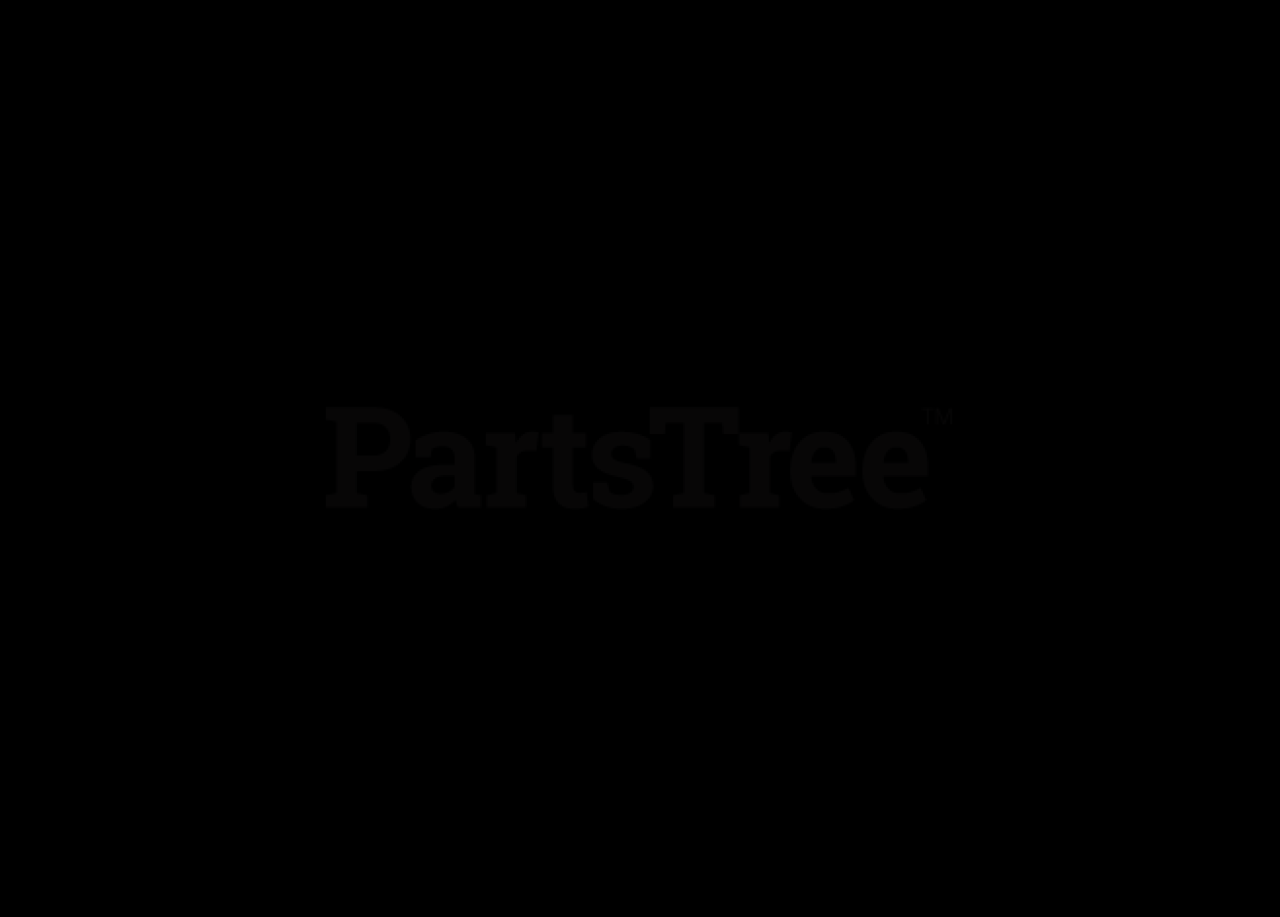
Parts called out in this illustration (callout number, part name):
1	Lift, Mower
2	Ring, Retaining External 1.00 x .078
3	Bushing, Flange 1.00 x 1.12 x .75 x 1.375
4	Key, Woodruff .25 x 1.00
5	Washer, Flat Steel 1.062 x 2.00 x .134
6	Weldment, Lift Arm-Front
7	Weldment, Rear Lift Arm – Left Hand
8	Bushing, Flange Nylon .762 x 1.0 x .58 x 1.48
9	Washer, Hardened Steel .758 x 1.23 x .031
10	Ring, Retaining-External .689 x .077
11	Weldment, Rear Lift Arm – Right Hand
12	Rod, Lift Assist 19.35"
13	Pin, Roll .25 x 1.25 Stainless Steel
14	Washer, Flat Steel .630 x 1.25 x .062
15	Washer, Flat Steel .812 x 1.50 x .135
16	Washer, Hardened Thrust 1.00 x 1.55 x .03
